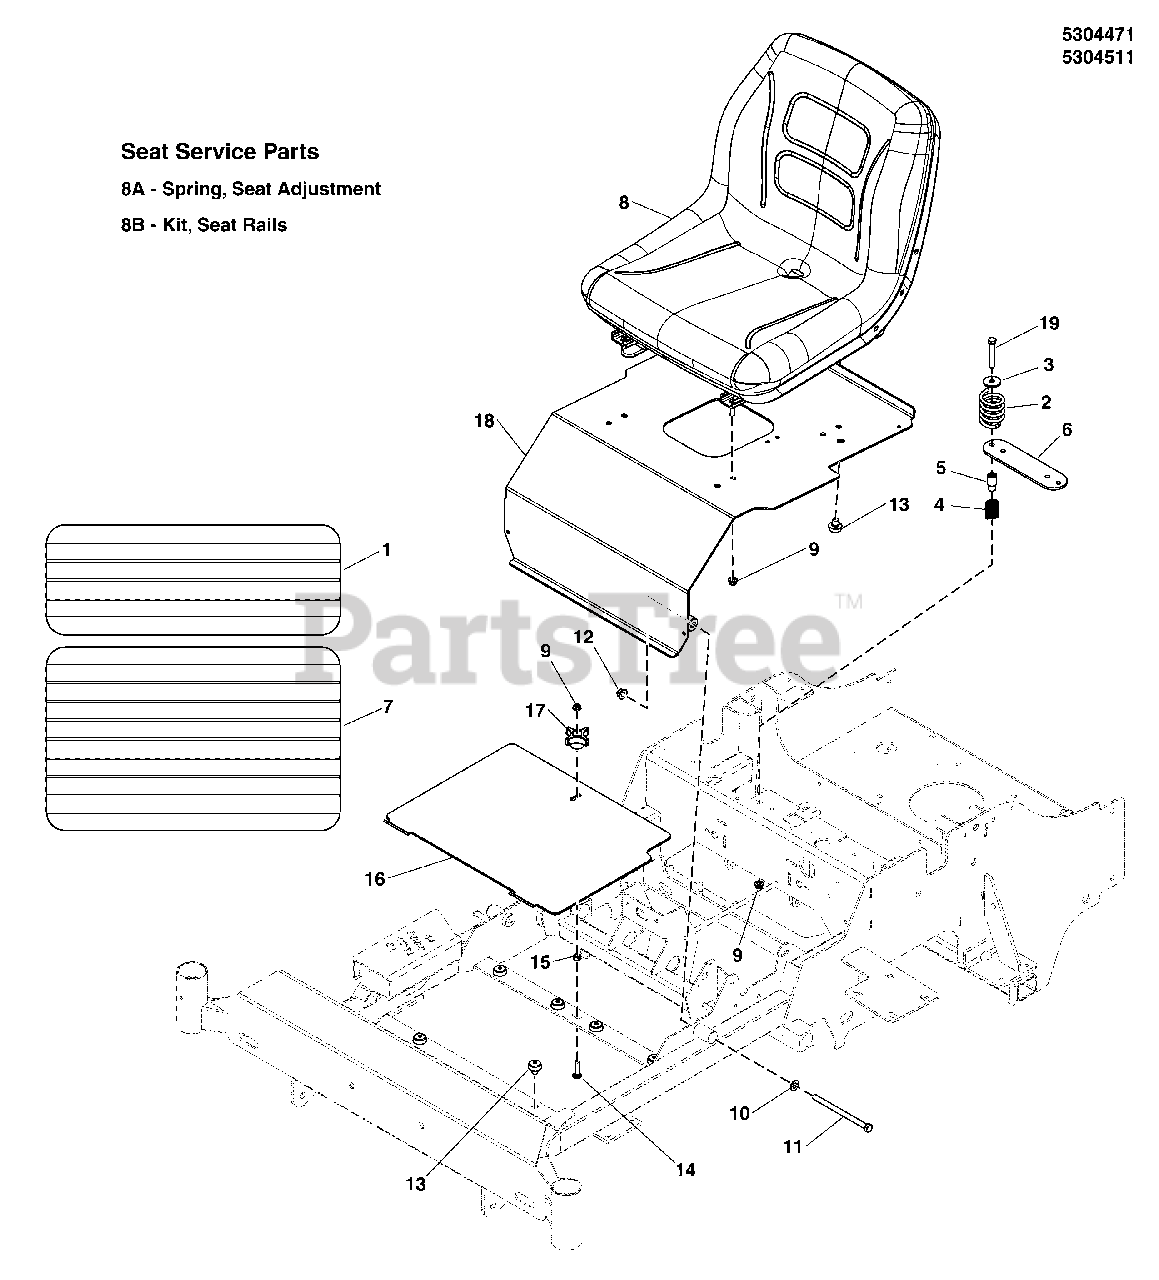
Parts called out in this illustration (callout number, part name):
1	SAFETY WALK, FLOOR REST, 6.00 X 16.00
2	SPRING, SEAT SUPPORT
3	WASHER, .34 X 1.25 X 10 GA
4	SPRING, COM 720ID X 1.31KG X .118WIRE
5	SPACER, .33 X .66 X 1.31 SHLDR, CZ
6	PLATE, SEAT SWITCH, RED
7	SAFETY WALK, FLOOR PLATE, 16.00 X 10.00
8	SEAT, NO ARM REST
8A	SPRING, Extension, Seat Adjustment (BLK or SLVR) (3-1/2" Total unstretched length.)
8B	SEAT RAIL, KIT, RH AND LH (SV)
9	NUT, 5/16-18 HEX NYLOCK FLANGE
10	WASHER, 3/8 SAE
11	BOLT, 3/8-16 X 5-1/2 GD5 CZ
12	NUT, Hex Flange, Nylock, 3/8-16
13	MNT, VBRTN, RBBR
14	BOLT, 5/16-18 X 1-1/4, CARRIAGE YZ
15	NUT, 5/16-18, HEX, CNTR LK,ZINC PHOS/OIL (80003675)
16	PLATE, FLOOR, REMOVABLE - RED
17	KNOB-INT THR, .312-18 4-ARM 2.12WD 1.06LG
18	ASSM, SEAT PLATE W/ DECAL, ZTX550 CE
19	BOLT, 5/16-18 X 2-1/4 GD5 YZ
